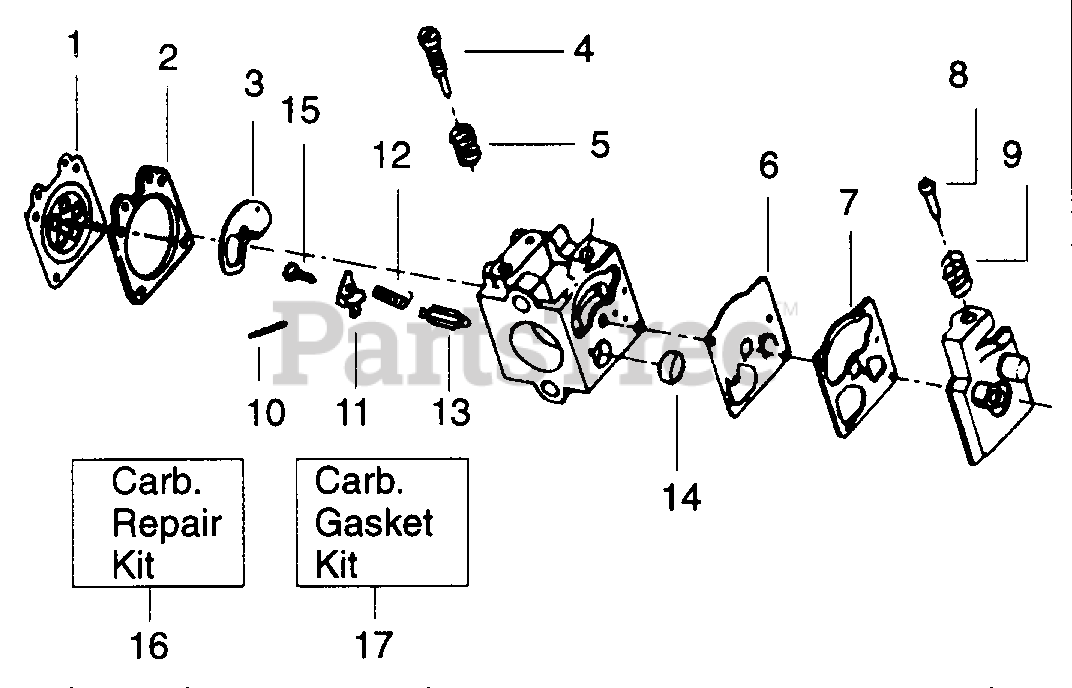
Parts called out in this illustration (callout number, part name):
1	Metering Diaphram
2	Metering Diaphragm Gasket
3	Circuit Plate Gasket
4	Mixture Needle
5	Mixture Needle Spring
6	Fuel Pump Diaphragm
7	Fuel Pump Gasket
8	Idle Speed Screw
9	Idle Speed Spring
10	Metering Lever Pin
11	Metering Lever
12	Metering Lever Spring
13	Inlet Needle Valve
14	Fuel Inlet Screen
15	Metering Lever Pin Screw
16	Carb. Kwik Repair Kit (Inc. 1,2,3,6,7,10,11, 12,13,14,15)
17	Carb. Gasket/Diaphragm Kit (Inc. 1,2,3,6,7)
